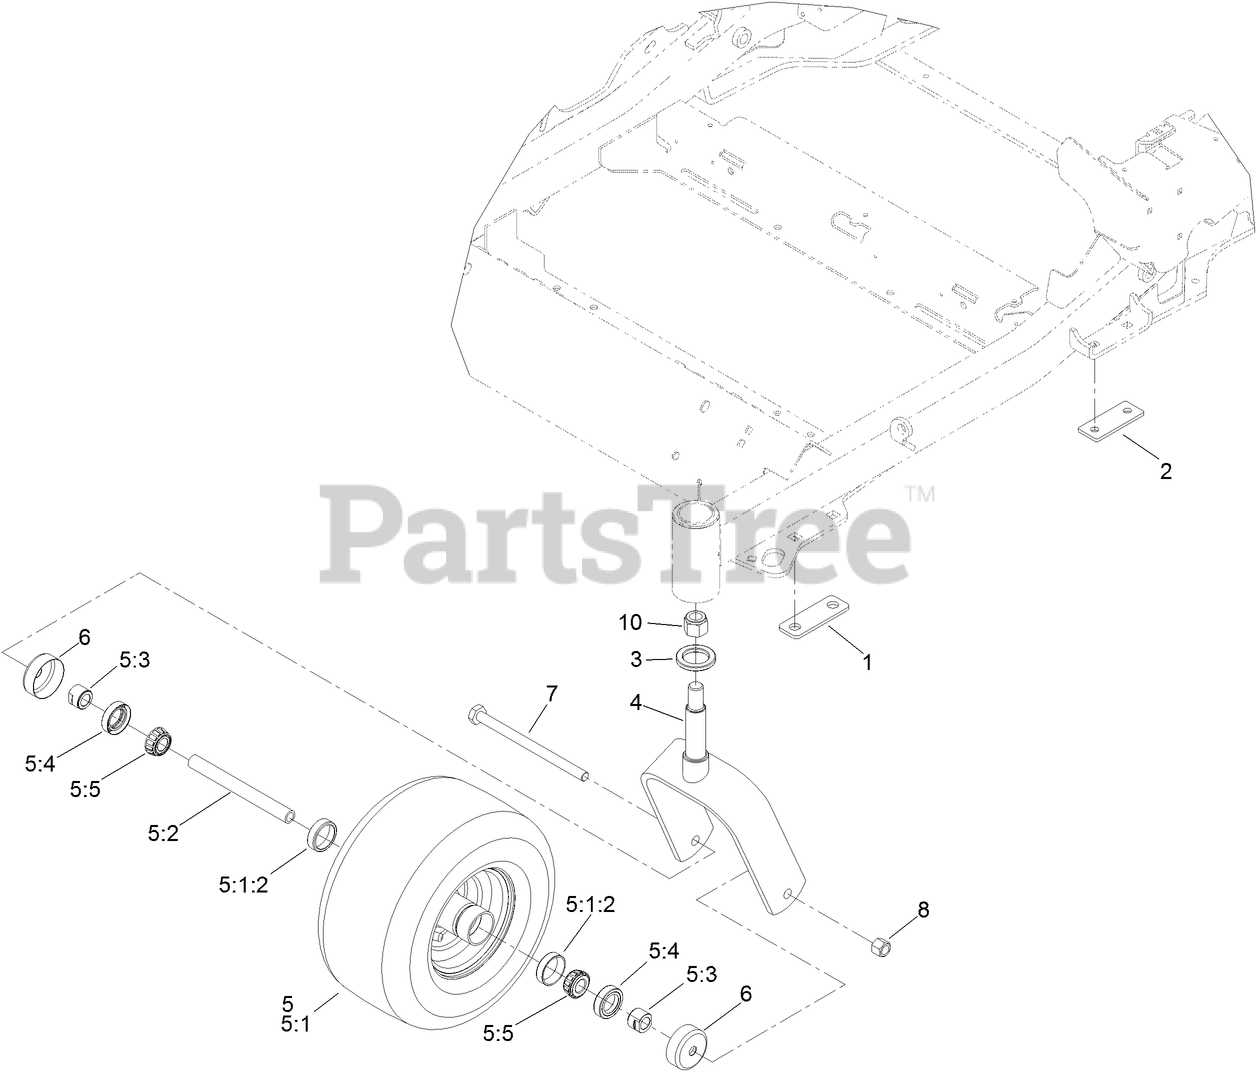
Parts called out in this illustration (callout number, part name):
1	SPACER-DECKLIFT, FRONT
2	SPACER-DECKLIFT, BACK
3	SEAL-GREASE
4	FORK-CASTER
5	WHEEL AND BEARING ASM
5:1	WHEEL AND TIRE ASM
5:1:2	BEARING-CUP
5:2	AXLE-CASTER
5:3	SPACER-NUT
5:4	SEAL-CASTER
5:5	BEARING-CONE, TAPER
6	GUARD-SEAL
7	SCREW-HH
8	NUT-LOCK, NI
10	NUT-LOCK, NI
